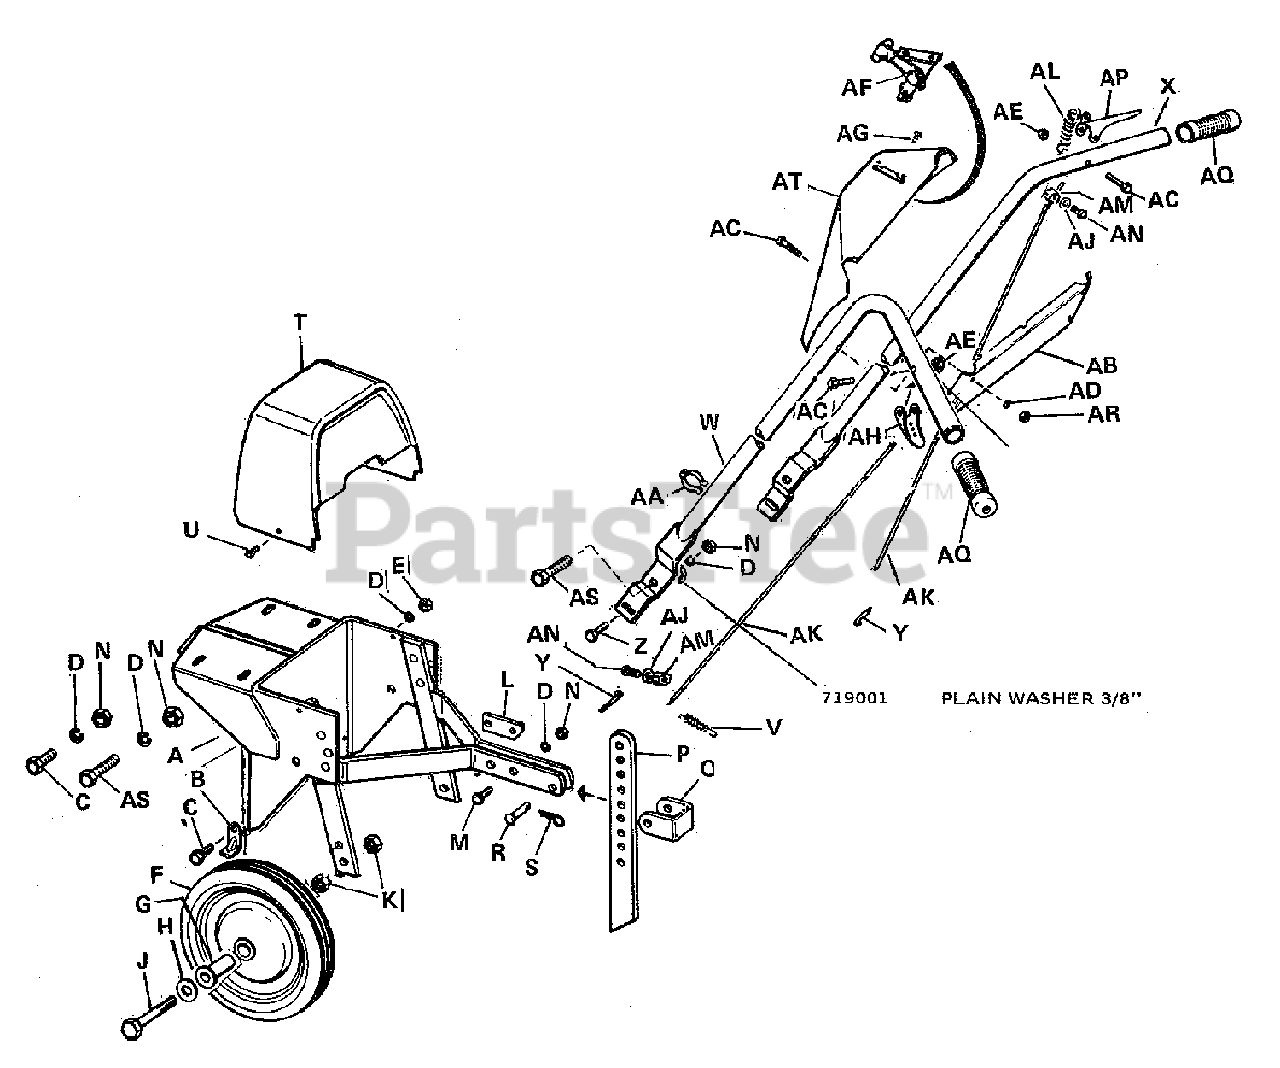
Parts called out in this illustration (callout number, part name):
A	BODY ASSEMBLY
C	CAPSCREW, Hex, Head, 3/8"-16 NC x 3/4" Lg
D	LOCKWASHER, 3/8"
E	NUT, Hex, Full, 3/8"-16
F	WHEEL & TIRE ASSEMBLY
G	BUSHING, Wheel
H	PLAIN WASHER, 1/2"
J	CAPSCREW, Hex, Head, 1/2"-13 NC x 3-1/4" Lg
K	NUT, Hex, Jam, 1/2"-13
L	PLATE, Stop
M	CAPSCREW, Hex Head, 3/8"-16 NC x 1-1/2" Lg
N	NUT, Hex, 3/8"-16
P	BAR, Depth
S	CLIP, Spring
U	SCREW, Washer Head, Threaded, 1/4"-20
W	HANDLE, L.H.
X	HANDLE, R.H.
Y	PIN, Cotter, 3/16" x 1"
Z	CAPSCREW, Hex, Head, 3/8"-16 NC x 1" Lg.
AA	CABLE, Clip
AB	HANDLE BAR, Cover
AC	CAPSCREW, Hex, Head, 1/4"-20 NC x 1-1/2" Lg.
AD	LOCK WASHER, 1/4"
AE	NUT, Hex, Full Lock, 1/4"-20
AF	THROTTLE CONTROL ASSEMBLY
AG	SCREW, Self Tapping, No. 10-24
AH	GRIP, Clutch-Reverse
AJ	PLAIN WASHER, No. 10-24 x 1/2"
AK	CONTROL WIRE
AM	CLAMP, Wire
AN	SET SCREW, No. 10-24 x 1/2"
AP	GRIP, Clutch-Forward
AQ	GRIP, Handle Bar
AR	NUT, Hex, Full, 1/4"-20 NC
AS	CAPSCREW, Hex, Head, 3/8"-16 NC x 1-1/4"
AT	CONTROL HOUSING ASSEMBLY
